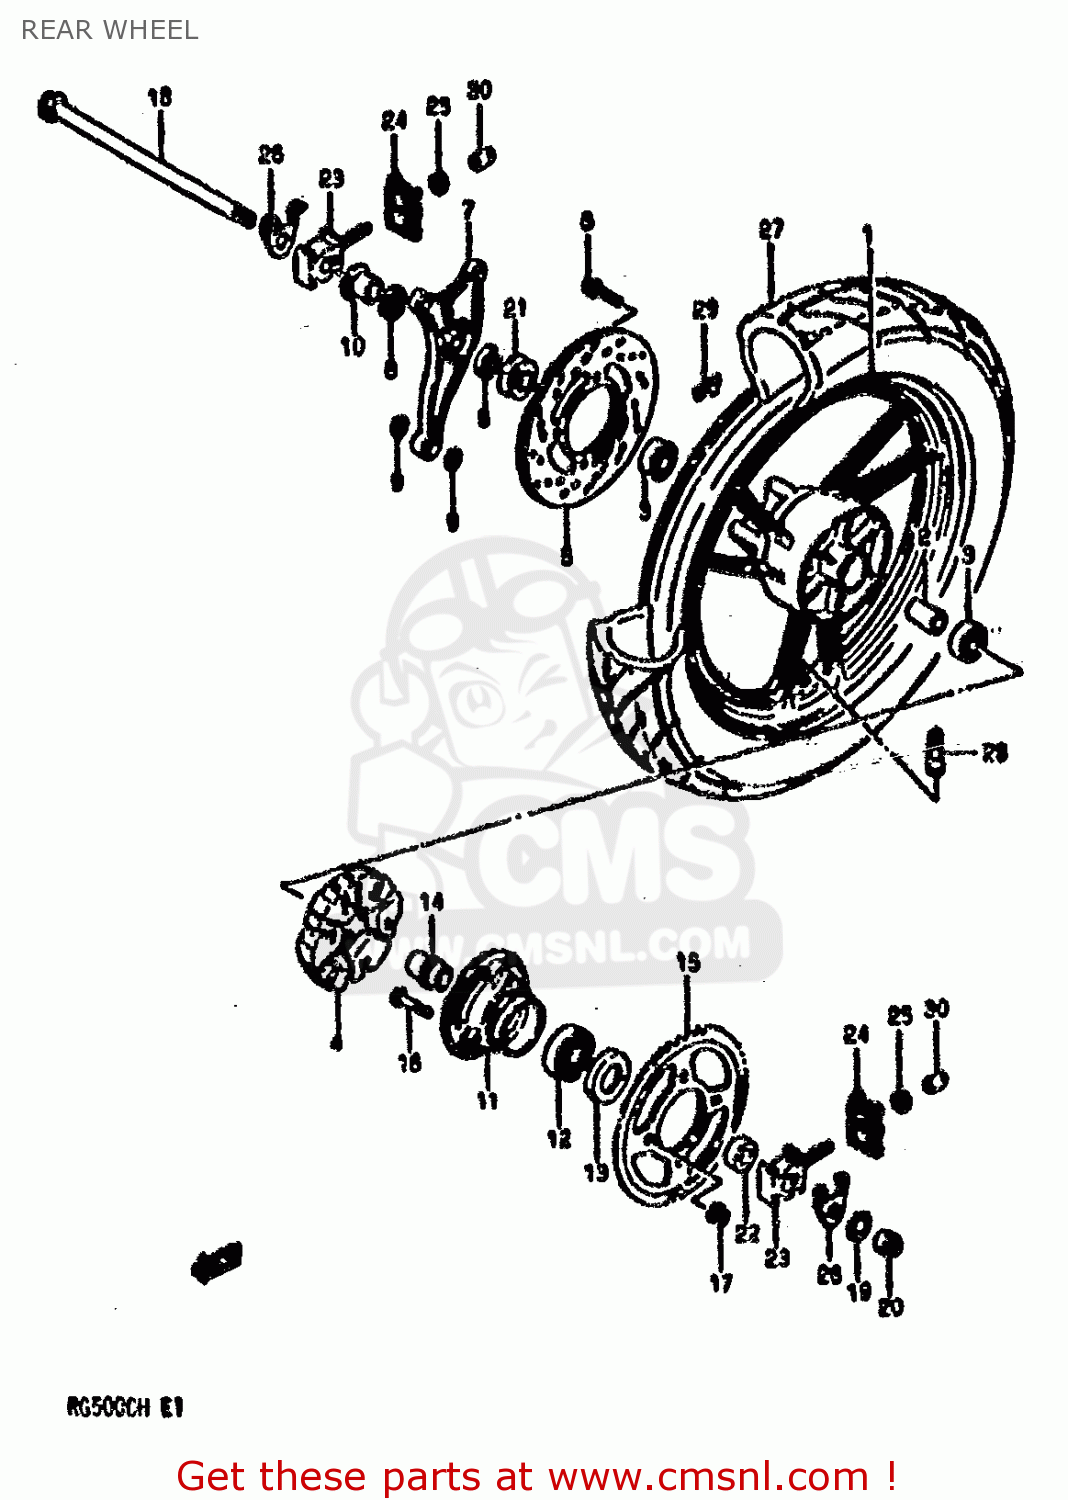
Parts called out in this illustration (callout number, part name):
1	WHEEL,REAR (NT2.75X17) (BLACK)
2	SPACER(17.5X25X102)
3	BEARING
4	ABSORBER,RR HUB,SHOCK
5	DISC,REAR BRAKE (BLACK)
6	BOLT
7	BRACKET,REAR CALIPERS
8	SEAL,OIL(24X31X5)
9	SEAL,RR CUSHION ROD LWR
10	SPACER,CALIPERS BRACKET
11	DRUM,REAR SPROCKET
12	BEARING
13	SEAL,OIL(35X62X8)
14	RETAINER,DRUM
15	SPROCKET,REAR (NT:40)
16	BOLT
17	NUT
18	AXLE,REAR
19	WASHER (17X30X3.2)
20	NUT 16MM
21	SPACER,RH
22	SPACER,LH
23	CHAIN ADJUSTER
24	PLAAT.SPANNER
25	NUT
26	WASHER,CHAIN ADJUSTER
27	TIRE,T/L REAR (120/90V17)
28	VALVE,TIRE
29	BALANCER,WHEEL
30	CAP,CHAIN ADJUSTER
